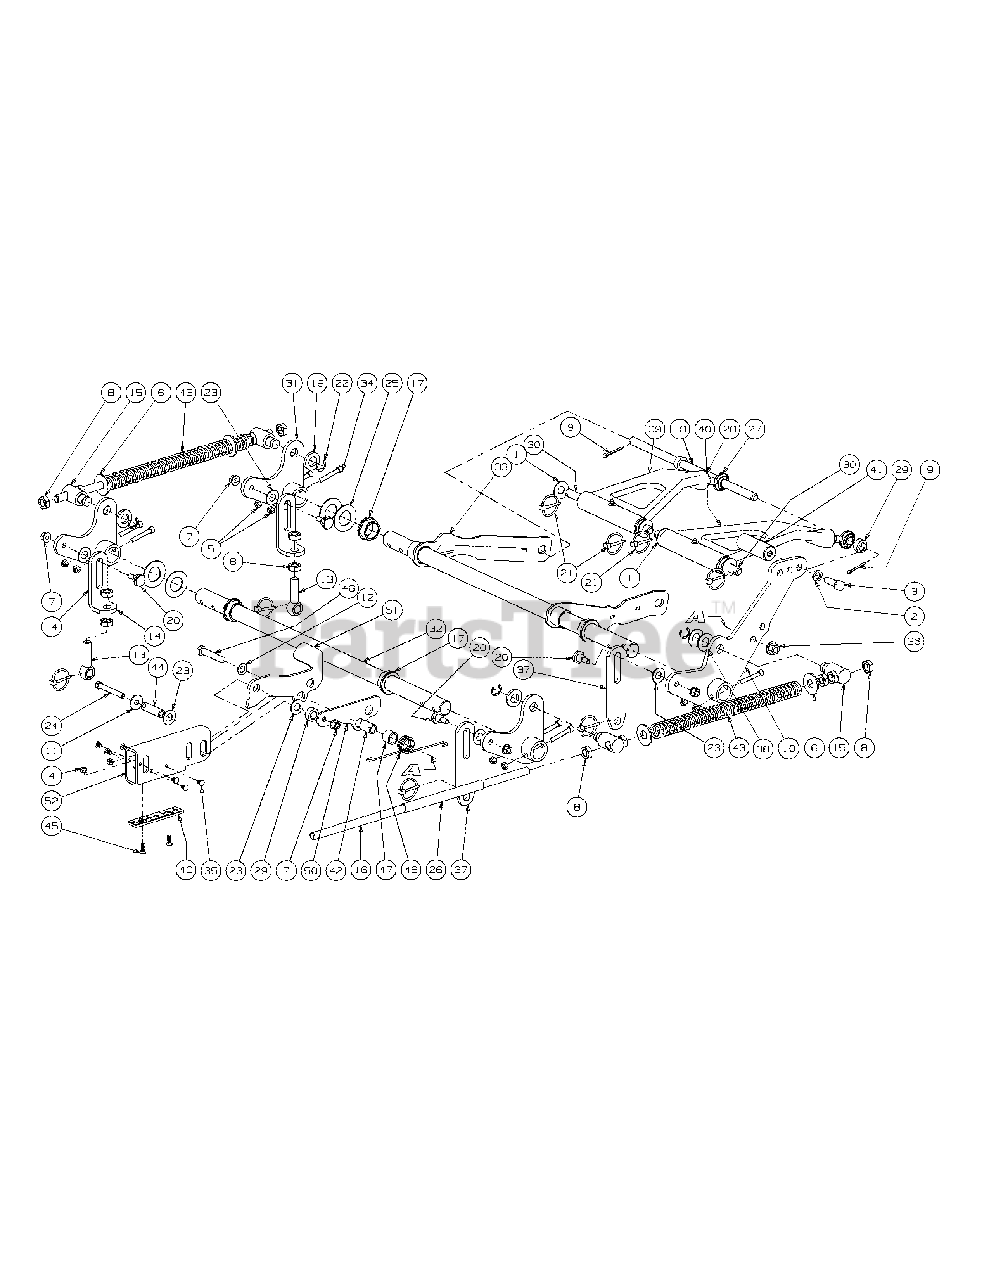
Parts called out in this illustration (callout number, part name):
1	Washer, 1.5 x .655 x .055
2	Lock Washer, 1/2
3	Hex Cap Screw, 1/2-13 x 1.50
4	Lock Nut w/Nylon Insert
5	Nut, 5/16-18, Nylock
6	Flat Washer, 5/8
7	Hex Nut, Flange Lock, 3/8-16
8	Jam Nut, 5/8-11
9	Cotter Pin, 3/16 x 1-1
10	Deck Lift Foot Pedal Weldment
11	Flat Washer, 1.25 x .411 x .100
12	Flat Washer, .536 ID x .930 OD x .05
13	Eye Bolt, 5/8ID
14	Eye Bolt, 5/8 ID
15	Ferule Lift
16	Lift Connector Rod
17	Hex Flange Bearing, 1.25 ID
18	Front Lift Link, Rod Mount
19	Spacer, .812 ID x .268 Lg.
20	Shoulder Screw, 0.625 OD x .437 Lg.
21	Linch Pin, 3/16 Dia.
22	E Clip, 3/4 Dia.
23	Nylon Flat Washer, 5/8
24	HHCS, 3/8-16, 3.00
25	Flat Washer, 1.25 ID
26	Hose, 5/8 ID 13/16 OD, 8" LG
27	Rod End, Male
28	Jam Nut, 5/8-18
29	Spacer, .630 ID x 1.06 OD x .440
30	Deck Lift Link Rod
31	Bellecrank Weldment Assembly
32	Deck Lift Shaft
33	Front Frame Strut Assembly
34	Socket Head CapScrew, 5/16-18 x 2
35	Rivet, 1/4 x 5/8
36	Nut, 1/2-13, FlangeLock
38	Washer, .76 x 1.49 x .06
39	Bearing Lift Brace Assembly, Left Hand
39	Grease Fittting
40	Bearing Lift Brace Assembly, Right Hand
40	Grease Fitting
41	Deck Lift Foot Pedal
42	Spacer, .51 ID x .75 OD x 1.240
43	Lift Compression Spring
44	Spacer, .375 ID x .625 OD x 1.53
45	Flat Head Cap Screw, 1/4-20 x .75
46	HHCS, 1/2-13 x 2.50
47	Spacer, .76 ID x 1.0 OD x .75
48	Torsion Spring, .120 Wire x 1.32 OD
49	Lift Wear Plate
51	Lift Link Bracket
52	Lift Tube, 3.0 x 1.5, 1" Height
